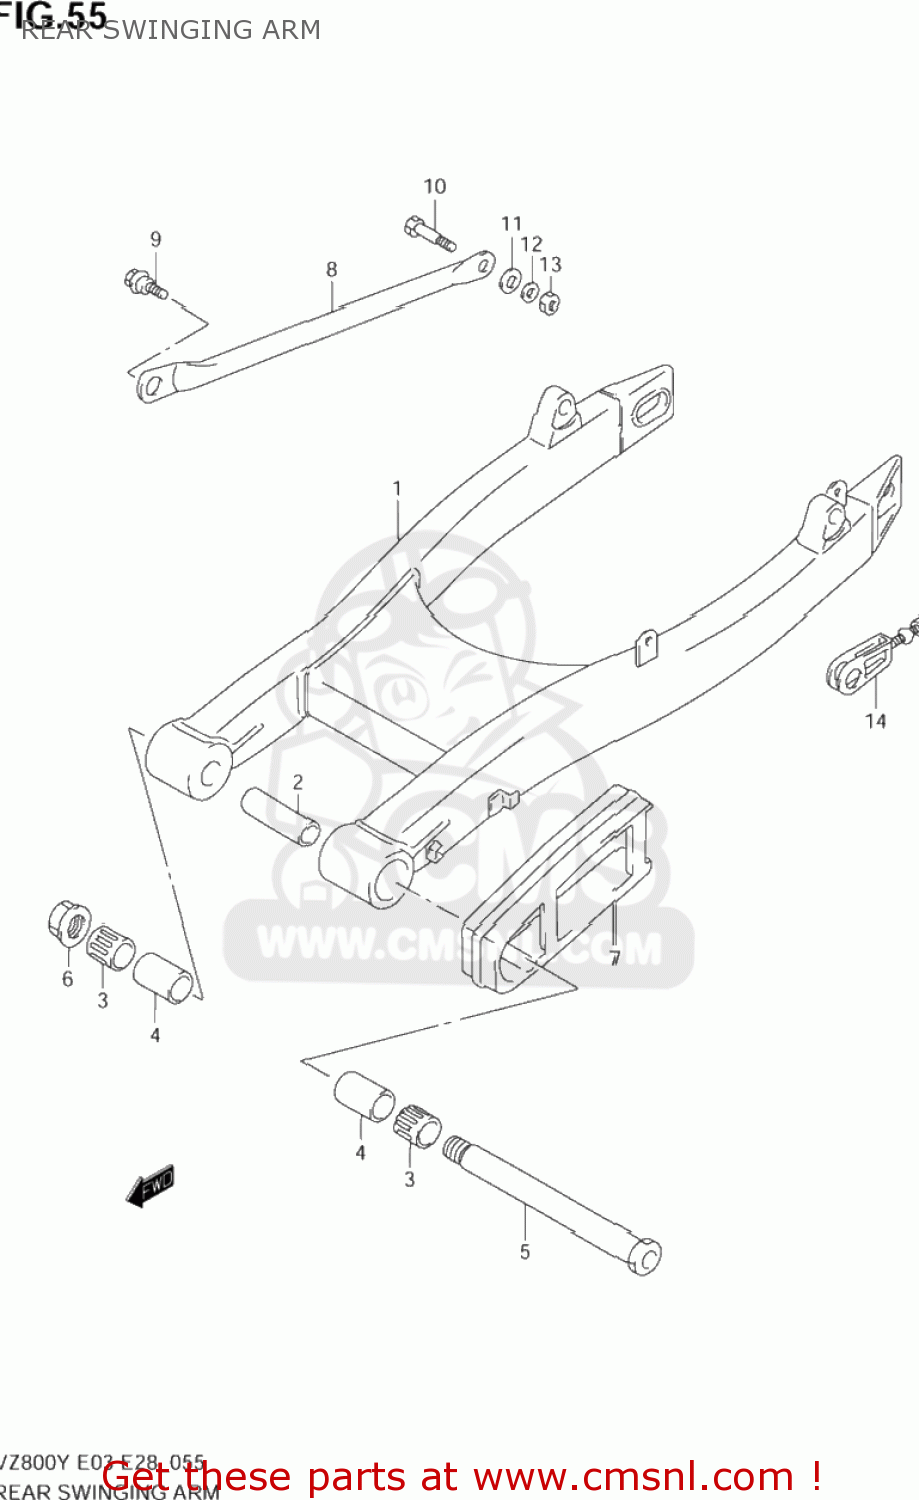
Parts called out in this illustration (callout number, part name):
1	SWINGINGARM,RR
2	SPACER,RR SWGARM PIVOT CTR
3	BEARING(25X33X35)
4	SPACER,RR SWGARM PIVOT
5	SHAFT,RR SWINGINGARM PIVOT
6	NUT ,18MM
7	BUFFER,CHAIN TOUCH DEFENSE
8	TORQUE LINK,RR
9	BOLT(10X30)
10	BOLT(10X41)
11	CUSHION
12	WASHER (10X20X2.3)
13	NUT
14	ADJUSTER ASSY,CHAIN
